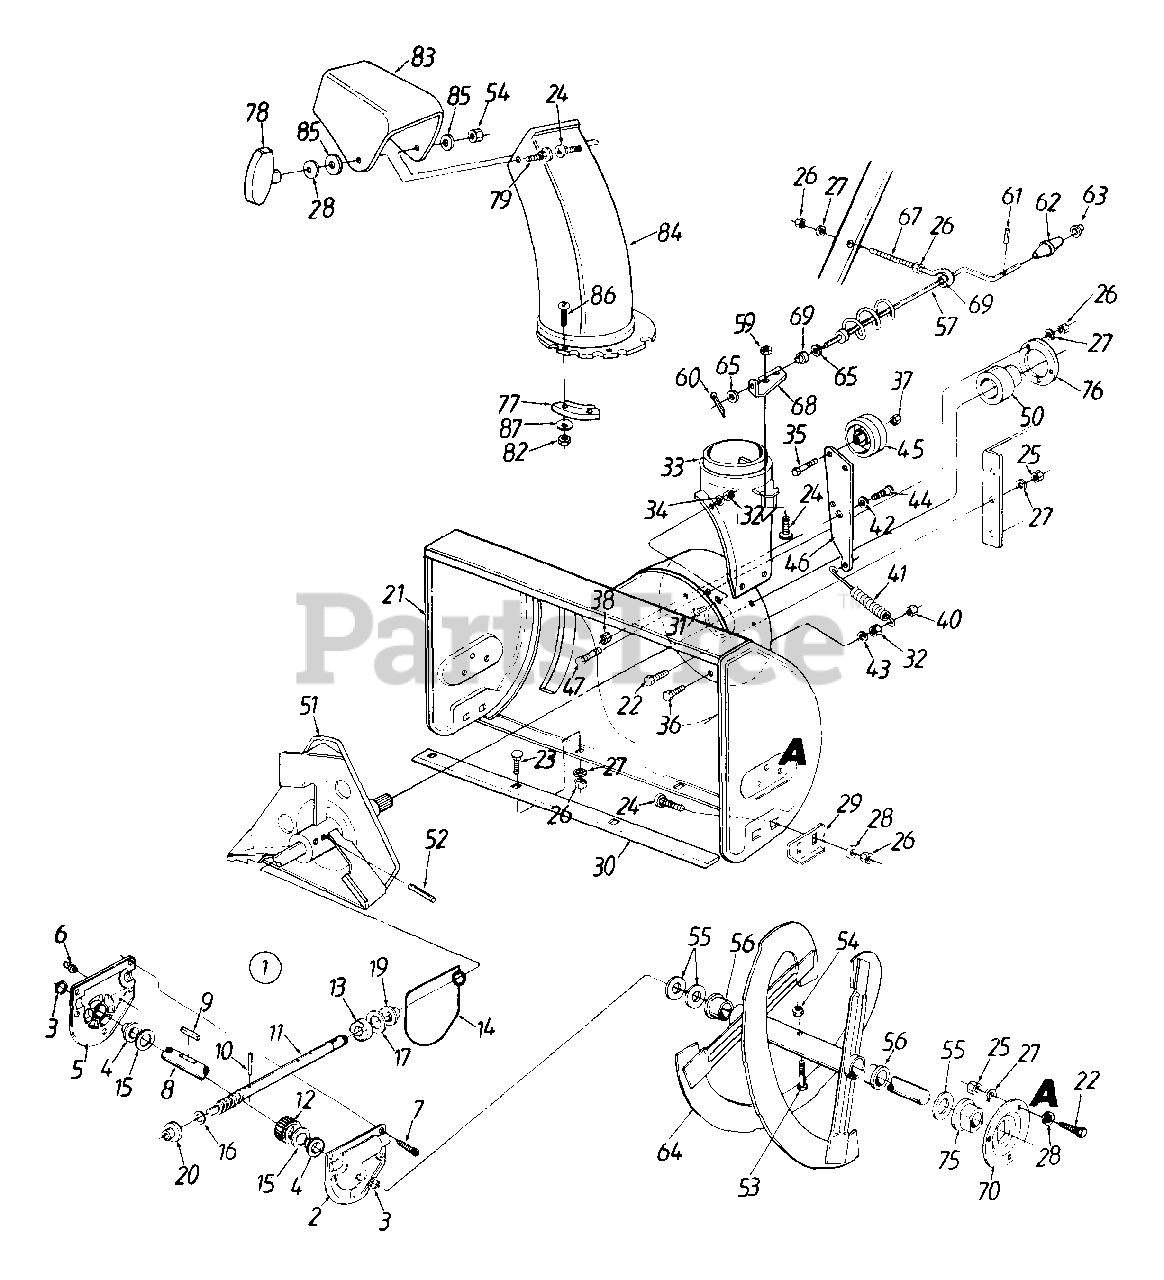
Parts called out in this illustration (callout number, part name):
1	Worm Drive Ass'y. Comp.
2	Reducer Housing -- L.H.
3	Oil Seal
4	Flange Bearing.75" I.D.
5	Reducer Housing -- R.H.
6	Grease Fitting
7	Hex TT-Tap Scr. 1/4-20 x .75" Lg.
8	24" Auger Shaft
9	#61 Hi-Pro Key 3/16" x 5/8" Dia.
10	Spiral Pin 1.25" Lg.
11	Impeller Shaft
12	Worm Gear
13	Thrust Collar
14	"O"-Ring (Special)
15	Fl-Wash..76" I.D. x 1.5" O.D.
16	Fl-Wash..5" I.D. x 1" O.D.
17	Fl-Wash..76" I.D. x 1.49" O.D.
19	Flange Bearing .75" I.D.
20	Flange Bearing .503" I.D.
21	24" Auger Housing Ass'y.
22	Hex Bolt 5/16-24 x .75" Lg.
23	Carriage Bolt 5/16-18 x .62" Lg.
24	Carriage Bolt 5/16-18 x .75" Lg.
25	Hex Nut 5/16-24 Thd.
26	Hex Nut 5/16-18 Thd.
27	L-Wash. 5/16" I.D.
28	Bell-Wash. .345" I.D. x .88" O.D.
30	24" Shave Plate
31	Truss Mach. Scr. 1/4-20 x .5" Lg.
32	Hex Nut 1/4-20 Thd."
33	Chute Adapter
34	Spring Washer 1/4" I.D.
35	Hex Bolt 3/8-24 x 1.5" Lg. (Gr. 5)
36	Hex Bolt 1/4-20 x .75" Lg. (Gr. 5)
37	Hex Ins. L-Nut 3/8-24 Thd.
38	Hex Top L-Nut 3/8-16 Thd.
40	Hex L-Nut 1/4-20 Thd.
41	Ext. Spring 3.6" Lg.
42	Wave Wash. .66" I.D. x.88"
43	L-Wash. 1/4" I.D.
44	Shld. Bolt .625" Dia. x .170" Lg.
45	Fl-Idler 2.75" O.D.
47	Hex Bolt 5/16-18 x 5/8" Lg.
50	Ball Bearing .75" I.D.
51	Blower Fan Ass'y.
52	Spiral Pin 1.5" Lg.
53	Shear Bolt 5/16-18 x 1.5" Lg.
54	Hex Cent. L-Nut 5/16-18 Thd.
55	Fl-Wash..76" I.D. x 1.49"
56	Flange Bushing .8" I.D.
57	Chute Crank Ass'y.
59	Hex Ins. L-Nut 5/16-18 Thd.
60	Cotter Pin 3/32" Dia. x .75"
61	Roll Pin 1/8" Dia. x .63" Lg.
62	Chute Crank Knob
63	Push Nut
65	Fl-Wash..385" I.D. x .62" O.D.
67	Eye Bolt 5/16-18 x 3" Lg.
69	Plastic Bushing .38" I.D.
75	Plastic Bearing w/Flats
76	Bearing Housing
77	Chute Flange Keeper
78	Knob Handle Ass'y.
79	Carriage Bolt 5/16-18 x 1" Lg.
82	Hex L-Nut 1/4-20 Thd.
83	Upper Chute
84	Lower Chute
85	Fl-Wash. .344" I.D. x 1.125"
86	Truss Mach. Scr. 1/4-20 x .75" Lg.
87	Fl-Wash. 1/4" I.D.
